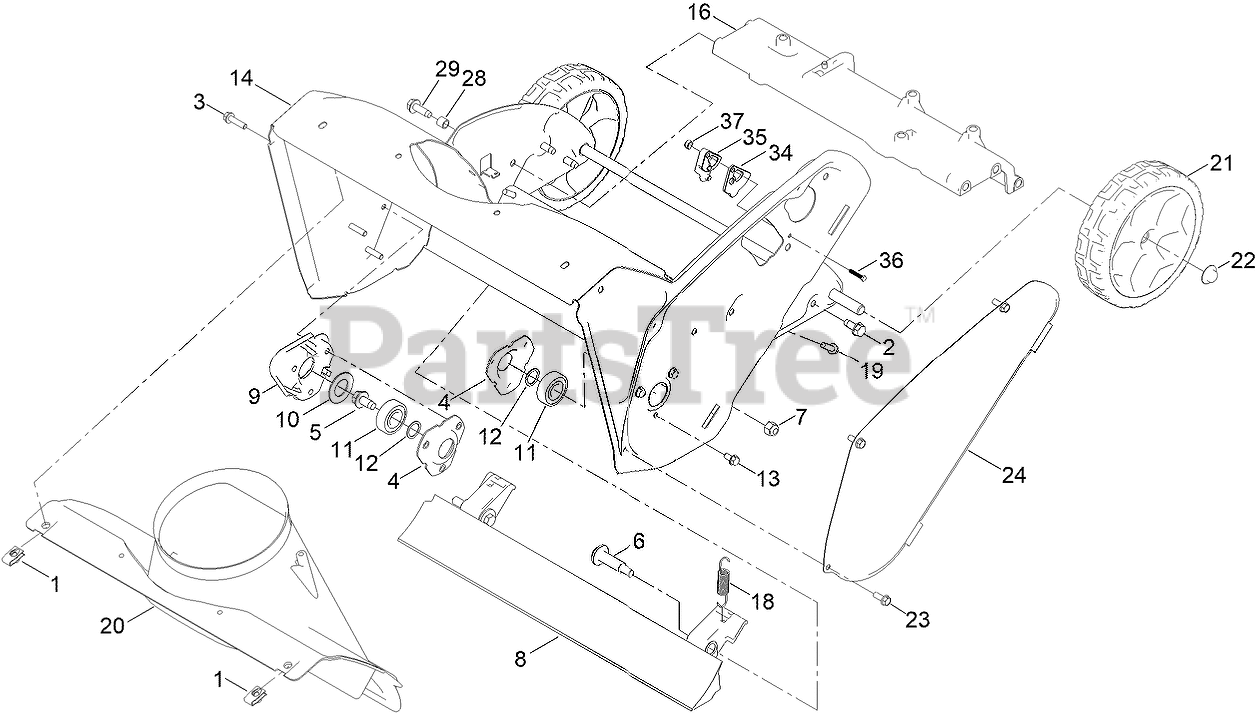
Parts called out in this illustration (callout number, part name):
2	SCREW-THD ROLL, HWH
3	SCREW-HWHTF
4	FLANGE-BEARING
5	SCREW-HWH
6	BOLT-SHOULDER
7	NUT-LOCK, NI
8	BLADE-SCRAPER
9	SPACER-BEARING, RH
10	WASHER-RUBBER
11	BEARING-BALL
12	WASHER-THRUST
13	SCREW-HWH
14	HOUSING-AUGER
16	BRACE-FRAME
18	SPRING-EXTENSION
19	SCREW-HWH
20	CHUTE-LOWER
21	WHEEL ASM, 7 INCH
22	NUT-PUSH
23	SCREW-HWH
24	COVER-BELT
28	SPACER-GROMMET
29	SCREW-HWHTF
34	CAP-GUIDE, CABLE
35	GUIDE-CABLE
36	Screw, Machine, Nozzle, 8-32 x 7/8"
37	NUT-LOCK
